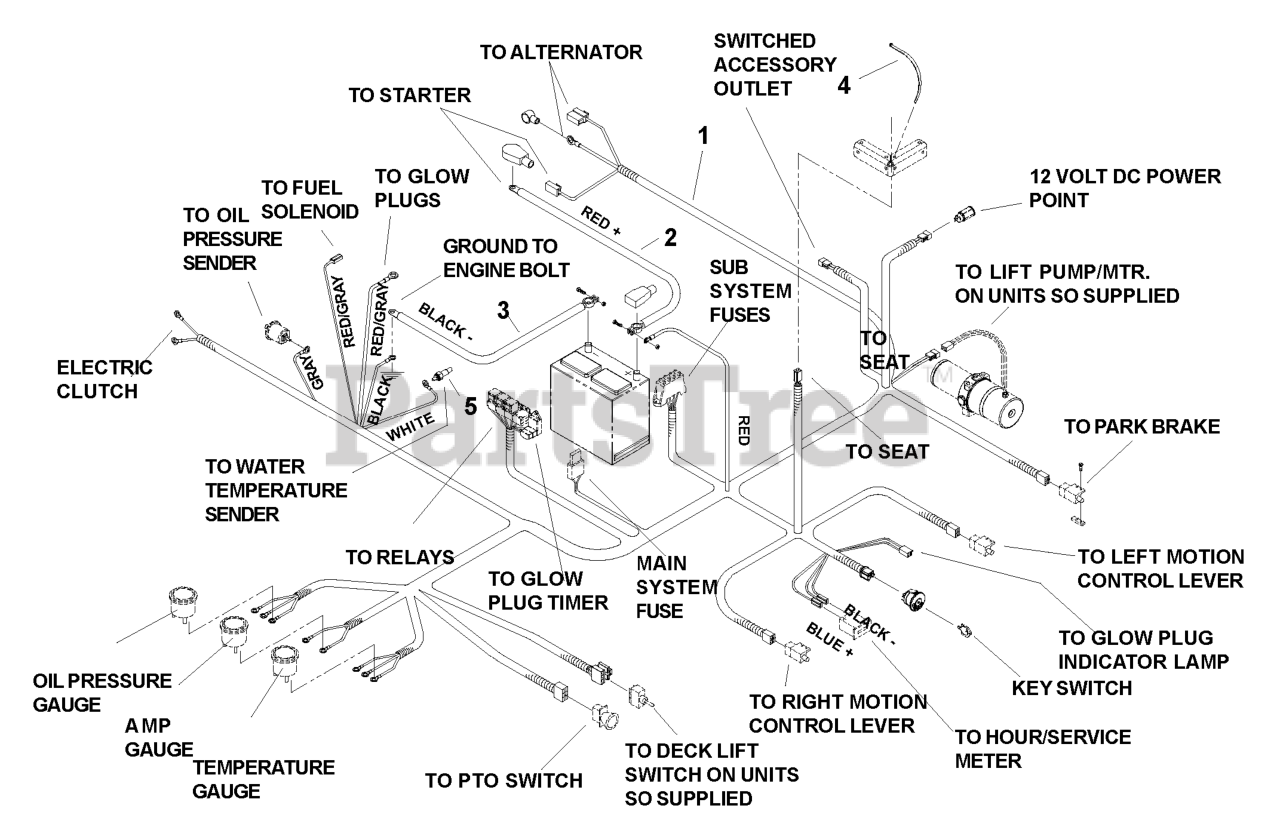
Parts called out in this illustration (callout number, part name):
2	CABLE, POS.
3	CABLE, NEG.
4	TIE, PLASTIC
5	SENDER,TEMP
